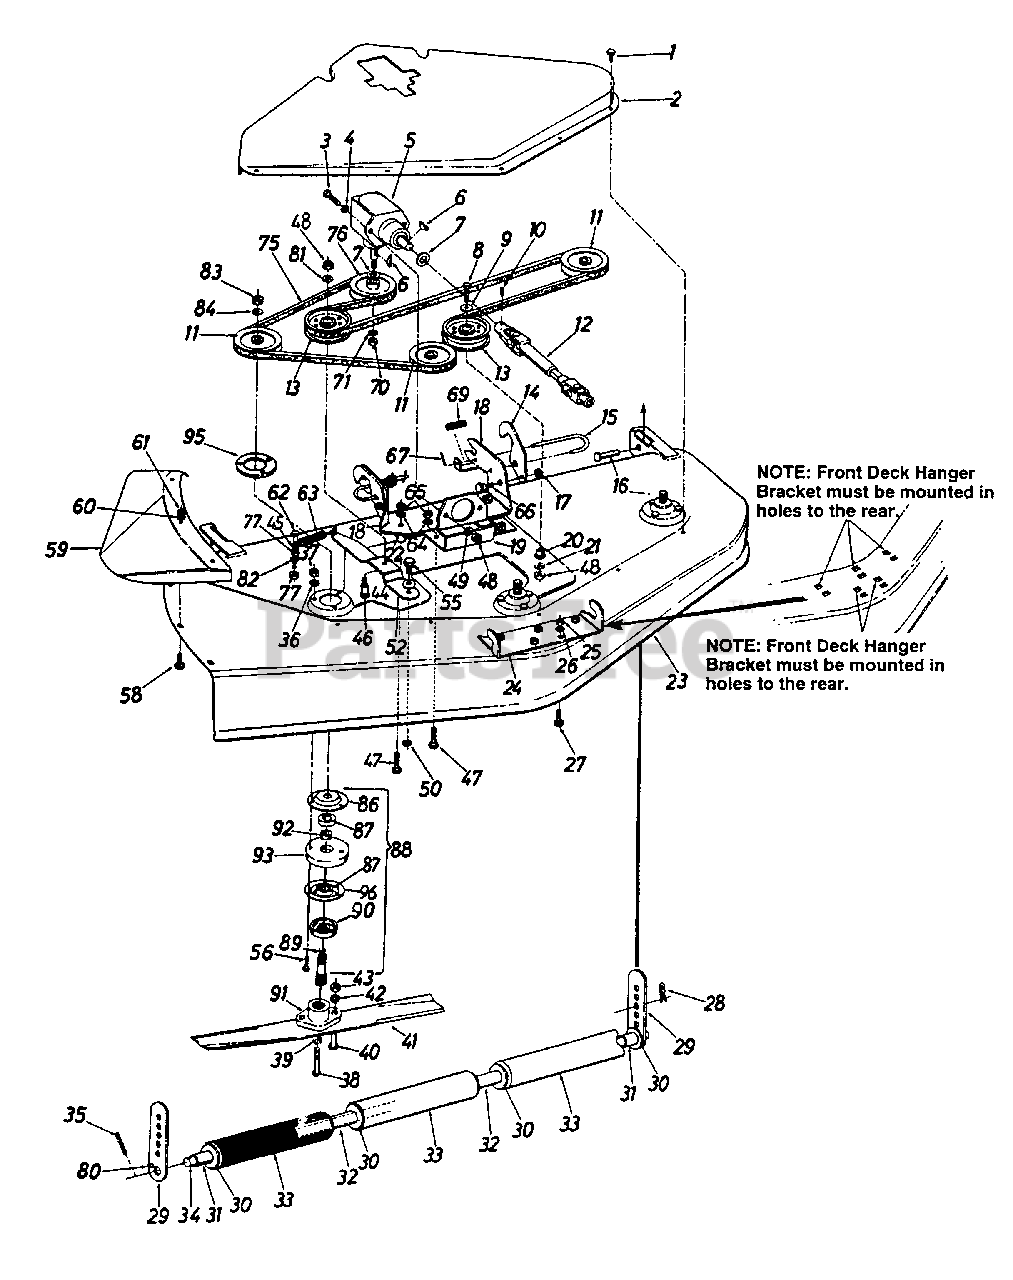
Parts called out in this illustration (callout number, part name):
1	Hex 8-Tap Scr. 1/4-20 x .38" Lg.
4	Ext. L-Wash. 3/8" I.D.
5	Right Angle Drive
6	#9 Hi-Pro Key 3/16 x 3/4" Dia.
7	Fl-Wash. 29/32" I.D.
8	Hex Bolt 3/8-16 x 2.25" Lg.
9	Fl-Wash. 3/8" I.D.
10	Sq. Hd. Set Scr. 3/8-16 x .50"
11	Deck Pulley
12	Universal Drive Shaft Ass'y.
12	Universal Drive Male Half
12	Universal Drive Female Half
13	Deck Idler Pulley
14	Hanger Lock
15	Release Pin
16	Clevis Pin .50" Dia.
17	Hex L-Nut 5/16-18 Thd.
21	L-Wash. 3/8" I.D.
22	Spacer .33" I.D. x .88" O.D.
26	L-Wash. 5/16" I.D.
27	Carriage Bolt 5/16-18 x .75" Lg.
28	Internal Cotter Pin
30	Fl-Wash. .75" I.D. x 1.5" O.D.
31	Spacer .758" I.D. x 1.25" O.D. x .530
34	Roller Shaft
35	Roll Pin 3/16 x 1.25"
36	L-Wash. 5/16" I.D.
37	Hex Cent. L-Nut 5/16-24 Thd.
38	Hex Self-Tap Scr. 3/8-24 x .75" Lg. (Gr. 5)
38	Hex Bolt 3/8-24 x .88" Lg. (Gr. 5)
39	L-Wash. 3/8" I.D. H.D.
40	Hex Bolt 5/16-24 x 1" Lg.
41	Blade 17"
42	L-Wash. 5/16" I.D.
43	Hex L-Nut 5/16-24 Thd.
44	Spr. Wash..445" I.D.
45	Fl-Wash. 1/4" I.D.
46	Shld. Scr. .625" Dia. x .96"
47	Carriage Bolt 5/16-18 x 1.5" Lg.
48	Hex Nut 3/8-16 Thd.
49	L-Wash. 3/8" I.D.
50	Hex L-Nut 7/16-14 Thd.
56	Hex Bolt 5/16-24 x 1.5" Lg. (Grade 5)
56	Screw-Rib Neck 5/16-24 x 1.12" Lg.
58	Carriage Bolt 5/16-18 x .75" Lg.
60	L-Wash. 5/16" I.D.
61	Hex Nut 5/16-18 Thd.
62	Hex Bolt 1/4-28 x 1-3/4" Lg.
63	Extension Spring
64	L-Wash. 5/16" I.D.
65	Hex Nut 5/16-18 Thd.
66	Shld. Bolt
67	Roll Pin 1/8" Dia.
69	Compression Spring
70	Hex L-Nut 5/8-18 Thd.
71	L-Wash. 5/8" I.D.
75	V-Belt 1/2"
76	Drive Pulley
77	Hex L-Nut 1/4-28 Thd.
80	Spring Pin Spiral 1/4" Dia. 1.00" Lg.
81	Bell-Wash. 3/8" I.D. x . 87" O.D.
82	L-Wash. 1/4" I.D."
83	Hex Jam Nut 5/8-18 Thd.
84	L-Wash. 5/8" I.D.
86	Bearing Housing
87	Ball Bearing
88	Deck Spindle Assembly 3/4"
88	Deck Spindle Assembly 1"
89	Spindle 3/4"
90	Bearing Shield
91	Blade Adapter 3/4"
91	Blade Adapter 1"
92	Spacer
95	Spindle Reinforcement Plate
96	Open Bearing Housing
96	Bearing Housing w/bearing 741-0919A
